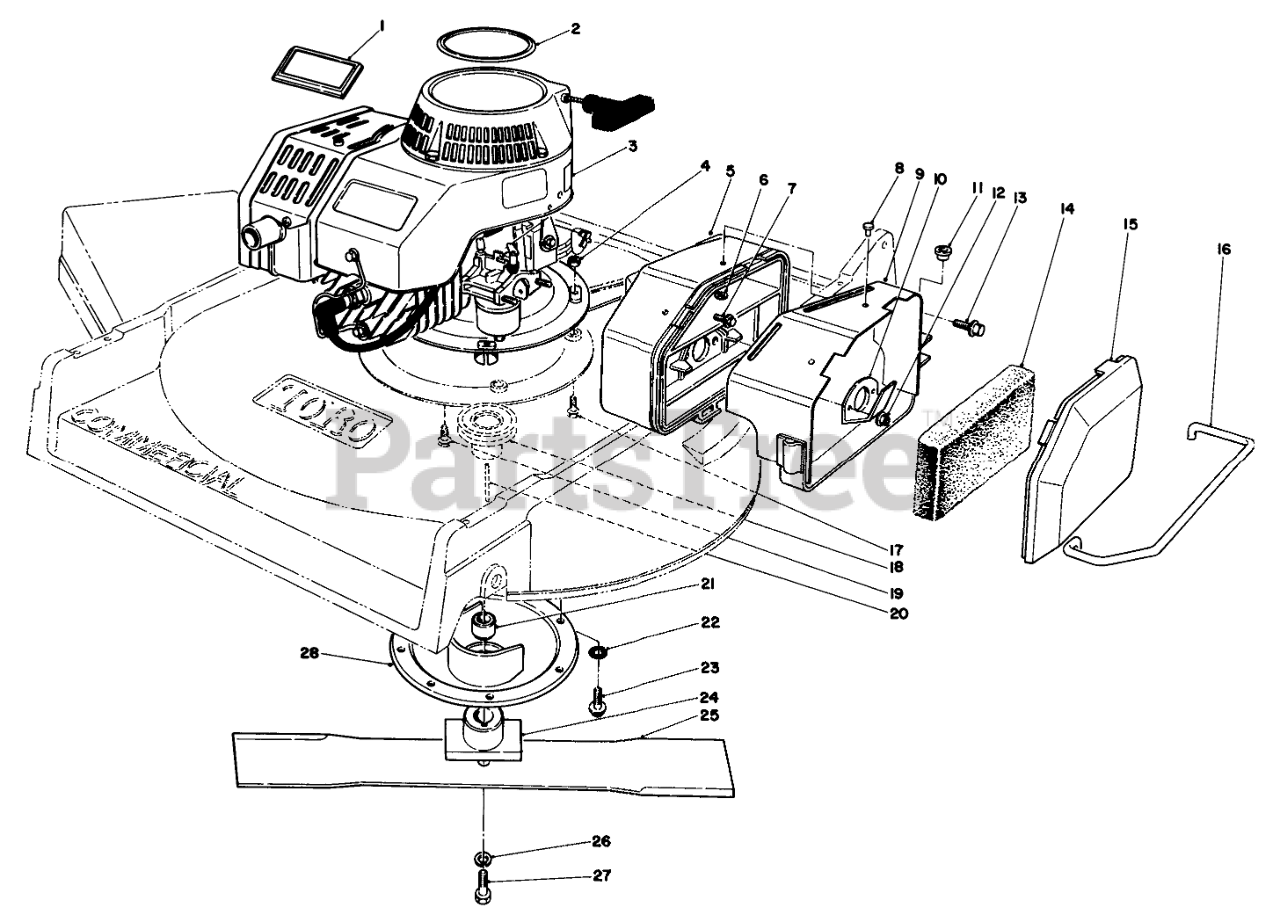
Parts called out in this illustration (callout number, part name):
1	Plate-Logo
2	Plate-Engine Logo
3	DECAL - FUEL
4	NUT-JAM
5	Air Cleaner Assembly (Incl. Ref. #6, 8, & 9)
6	WASHER-FLAT
7	HEX FL HD M.6X1.0X25MM
8	RIVET-POP
9	AIR CLEANER COVER WA
10	SPIT BACK DEFLECTOR
11	5/16 ID BSHG
12	NUT-LOCK
13	SCREW-HHF
14	FILTER
15	AIR CLEANER COVER
16	AIR CLEANER GUARD
17	SCREW-HH
18	PULLEY-DRIVER
19	SCREW-HH
20	KEY-SQUARE
21	BLADE SPACER
22	WASHER-LOCK, INTERNAL
23	SCREW-HWHTF
24	BLADE RETAINER WA
25	BLADE
26	WASHER-LOCK
27	SCREW-BLADE
28	PROTECTOR-CRANKSHAFT
